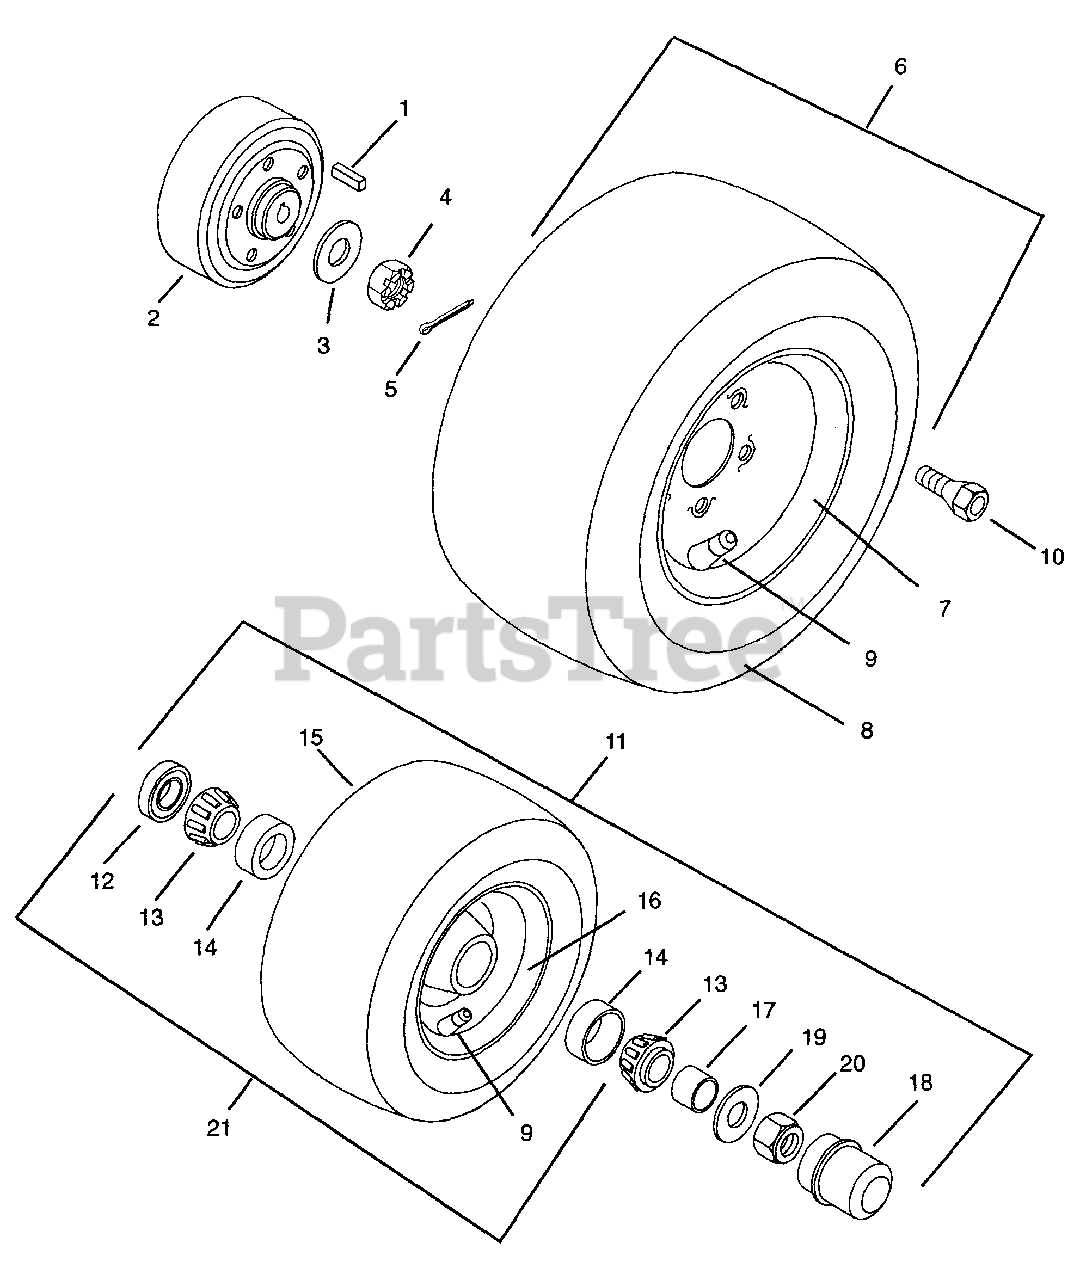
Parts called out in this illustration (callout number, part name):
1	Key-Feather .25 X 1.875 X .25
2	Hub, Wheel
3	Washer-Flat-Steel .812 X 1.50 X .139
4	Nut-Slotted .75-16
5	Pin-Cotter .18 x 1.50
6	Tire/Wheel Assembly 23 x 10.50-12
7	Tire, Rear 23 x 10.50-12
8	Weldment, Rim
9	Valve Stem Assembly
10	Bolt .44-20 x 1.0
11	Tire, Assembly
12	Seal 1.206 x 1.785 x .468
13	Bearing-Cone .750 x .61
14	Bearing-Cup 1.78 x .475
15	Tire 16 x 7.50-8
16	Weldment, Rim
17	Spacer .752 x 1.000 x .500
18	Dust Cap
19	Washer-Flat-Steel .656 x 1.31 x .095
20	Nut-Locking-Center .625-11
21	Tire/Wheel Assembly
